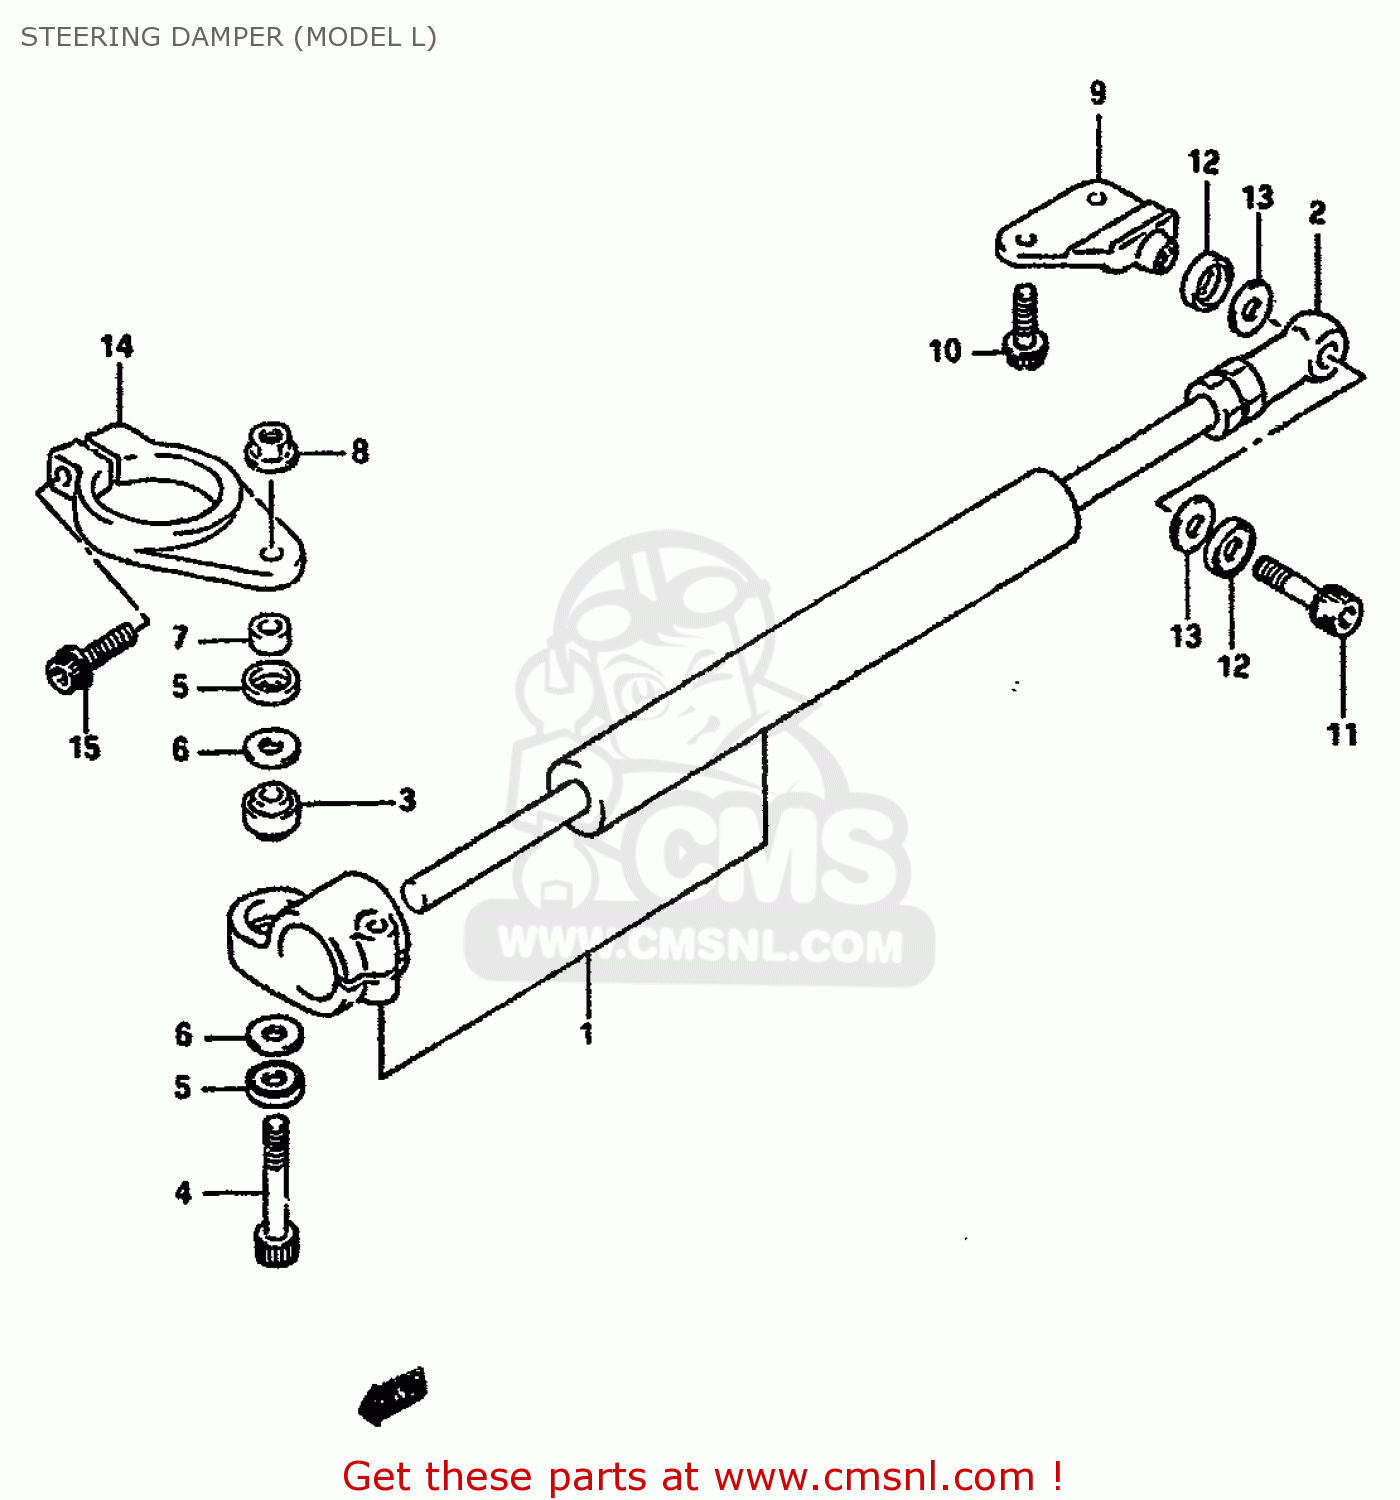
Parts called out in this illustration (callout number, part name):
1	DAMPER ASSEMBLY,STEERING
2	PILLOW BALL,ROD END
3	BEARING(8X17.5X11)
4	BOLT
5	6
6	SHIM
7	SPACER (8.4X14X6)
8	NUT
9	BOSS,STEERING DAMPER
10	BOLT
11	BOLT, FRONT RH
12	13
13	SHIM
14	BRACKET,STEERING DAMPER
15	BOLT
